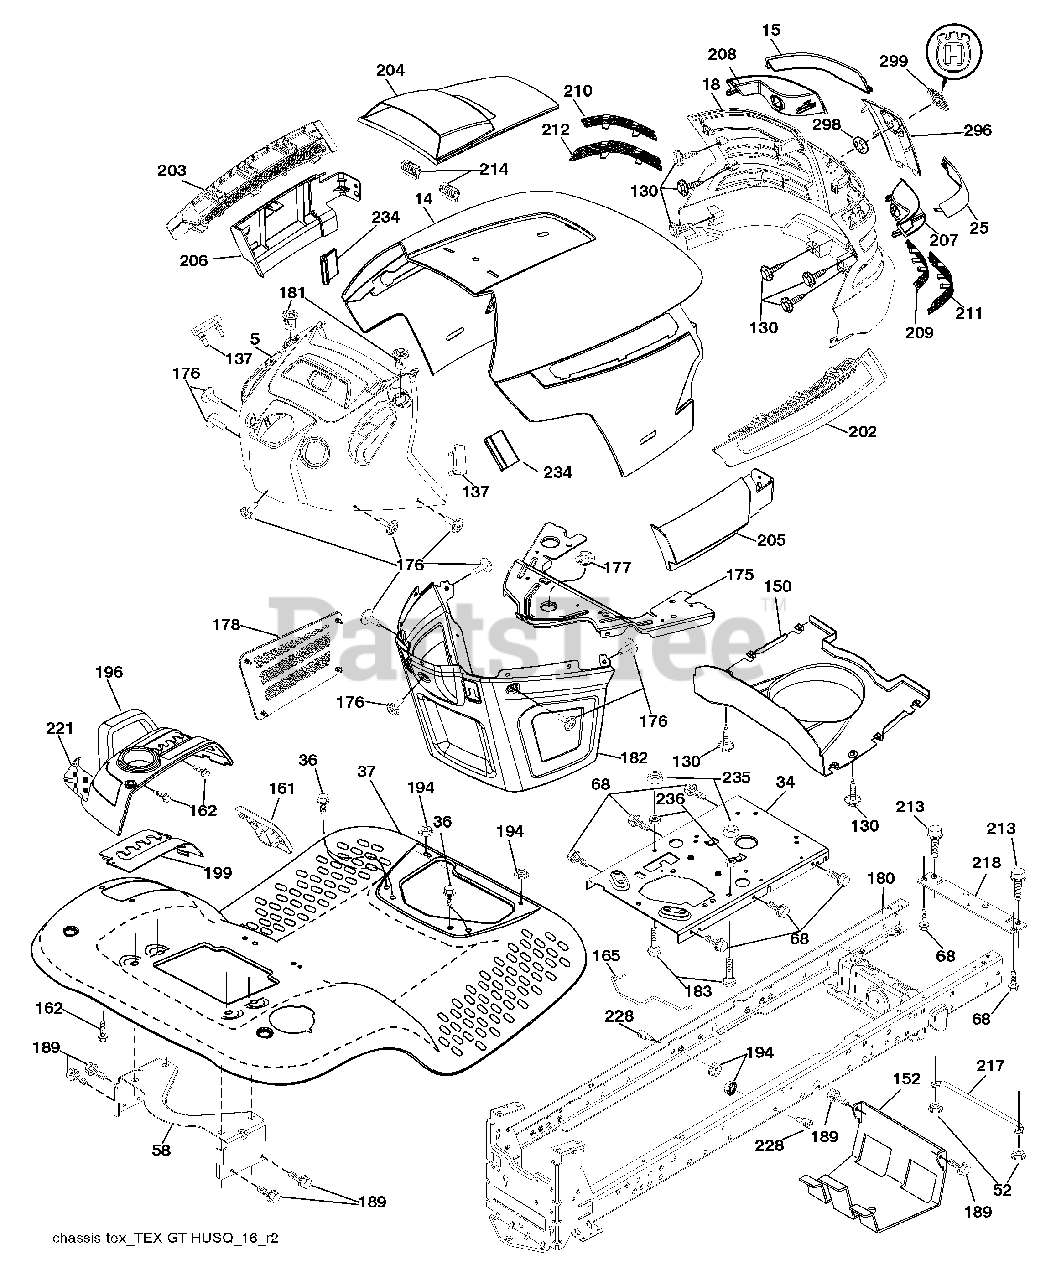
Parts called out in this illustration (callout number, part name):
14	Hood Asm.
18	Grille Asm.
34	Plate Engine
36	Screw 5/16-18 x 3/4
37	Fender
52	Nut Crown Lock 5/16-18
58	Bracket Fender
68	Screw 5/16-18 x 1/2
130	Screw #10 x .750 BOS Thread
137	Bumper Dash
150	Duct Heat Hood
152	Shield Browning/Debris
161	Console Fuel Window
162	Screw Hex Wsh Hi-Lo 1/4 x 1/2
165	Bracket Support Tank
175	Crossmember
176	Screw 10-24 x 5/8
177	Bushing Steering
178	Cargo Asm. Net
180	Chassis
181	Bushing Mtg. Fender Crgo.
182	Dash Lower
183	Bolt Fin Hex 5/16-18 unc x 1-1/4
189	Screw 5/16-18 x 3/4
194	Nut Lock Hex Flange 5/16-18
196	Console Asm. Deck Lift
199	Plate Deck Lift
202	Vent Side Hood RH
203	Vent Side Hood LH
204	Vent Asm Hood Top
205	Skirt Hood Side RH
206	Skirt Hood Side LH
209	Insert Hex Top RH
210	Insert Hex Top LH
211	Insert Hex Bottom RH
212	Insert Hex Bottom LH
213	Bolt Hex Hd 5/16-18 unc x 3/4
214	Clip Retainer
221	Reflector LH
228	Stud Fastener
234	Bumper Hood
235	Spacer Fender
236	Nut Center Lock 5/16-18 unc
299	Logo
